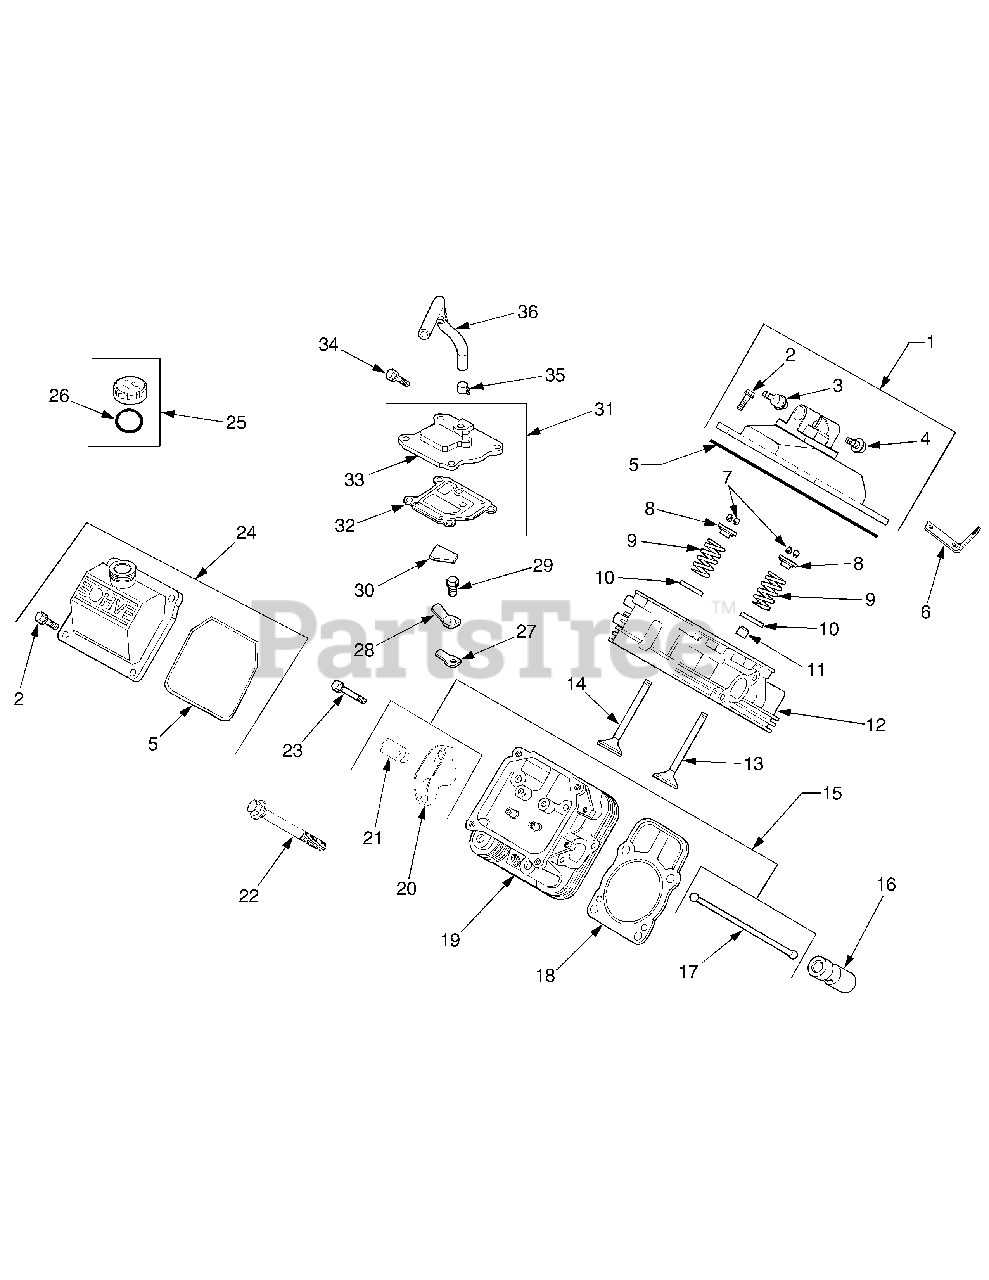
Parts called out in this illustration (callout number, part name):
1	Kit, Valve Cover (Includes 2-5) ...
2	Screw, Hx. Flng, M6 x 1.0 x 30 ...
3	Kit, 1/4" Fitting (45°)
4	Kit, 1/4" Fitting (90°)
5	O-Ring, Valve Cover
6	Strap, Lifting
7	Kit, Retainer
8	Cap, Valve Spring
9	Spring, Valve
10	Retainer, Spring
11	Seal, Valve Stem
12	Head Assembly, #1 Cylinder
13	Valve, Intake (Std.)
13	Valve, Intake (.25mm)
14	Valve, Exhaust (Std.)
14	Valve, Exhaust (.25mm)
15	Kit, Valve Train (Includes 17,20,21)
16	Lifter, Valve
18	Kit, Gasket, Cylinder Head
19	Head Assembly, #2 Cylinder
21	Pivot, Rocker Arm
22	Screw, Hex Flange M10-1.5 x 90
23	Screw, Hx. Flng, M6 x 1.0 x 34 ...
24	Cover, Valve - Oil Fill (Includes 22 and 24)
25	Cap Assembly, Oil Fill (Includes 26)
27	Reed, Breather
28	Retainer, Breather Reed
29	Screw, Hex Flange M5 x 0.8 x 10
30	Filter, Breather
31	Kit, Breather (Includes 32, 33)
32	Gasket, Breather
33	Cover, Breather
34	Screw, Hex Flange M6 x 1.0 x 20
35	Clamp, Breather
36	Hose, Breather
